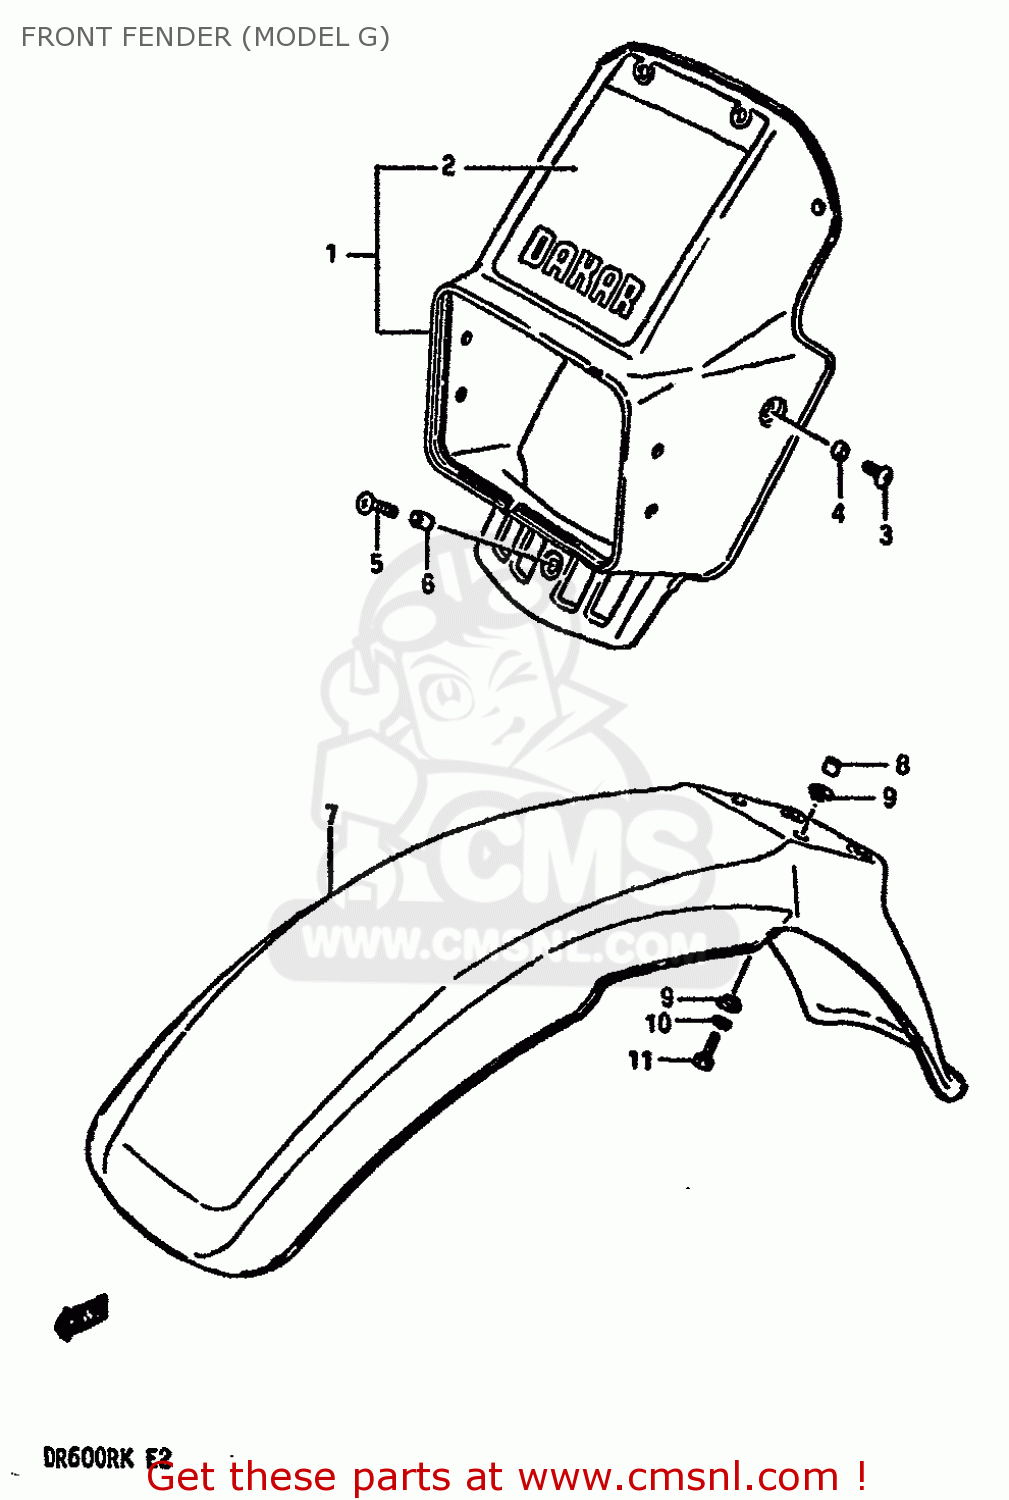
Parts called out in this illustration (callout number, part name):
1	COVER,HEADLAMP (WHITE)
2	TAPE SET
3	SCREW 6X12
4	SPACER (6.1X8X3.5)
5	SCREW, CENTER
6	SPACER (6.1X8X12)
7	FENDER, FRONT (WHITE)
8	SPACER(6.1X9X7.5)
9	WASHER
10	WASHER,LOCK
11	BOLT
